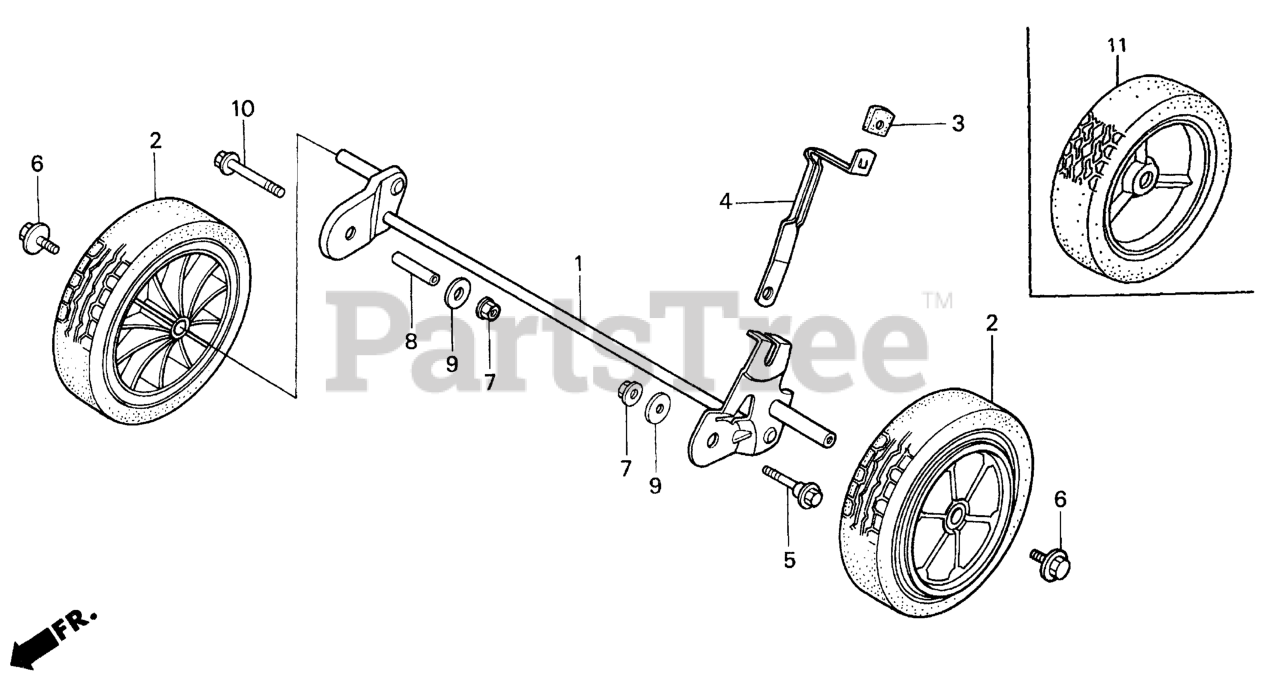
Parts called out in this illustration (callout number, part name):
1	SHAFT, RR. AXLE (NOT AVAILABLE)
2	WHEEL (7X1.5)
2	WHEEL (7")
3	GRIP, ADJUSTER
4	PLATE, RR. ADJUSTING
5	BOLT, ADJUSTING CENTER
6	BOLT, WHEEL
7	NUT, FLANGE (8MM)
8	COLLAR A, ADJUSTING CENTER
9	WASHER, PLAIN (8MM)
10	BOLT, FLANGE (8X50)
11	WHEEL (7") *NH31* (MCKINLEY WHITE)
